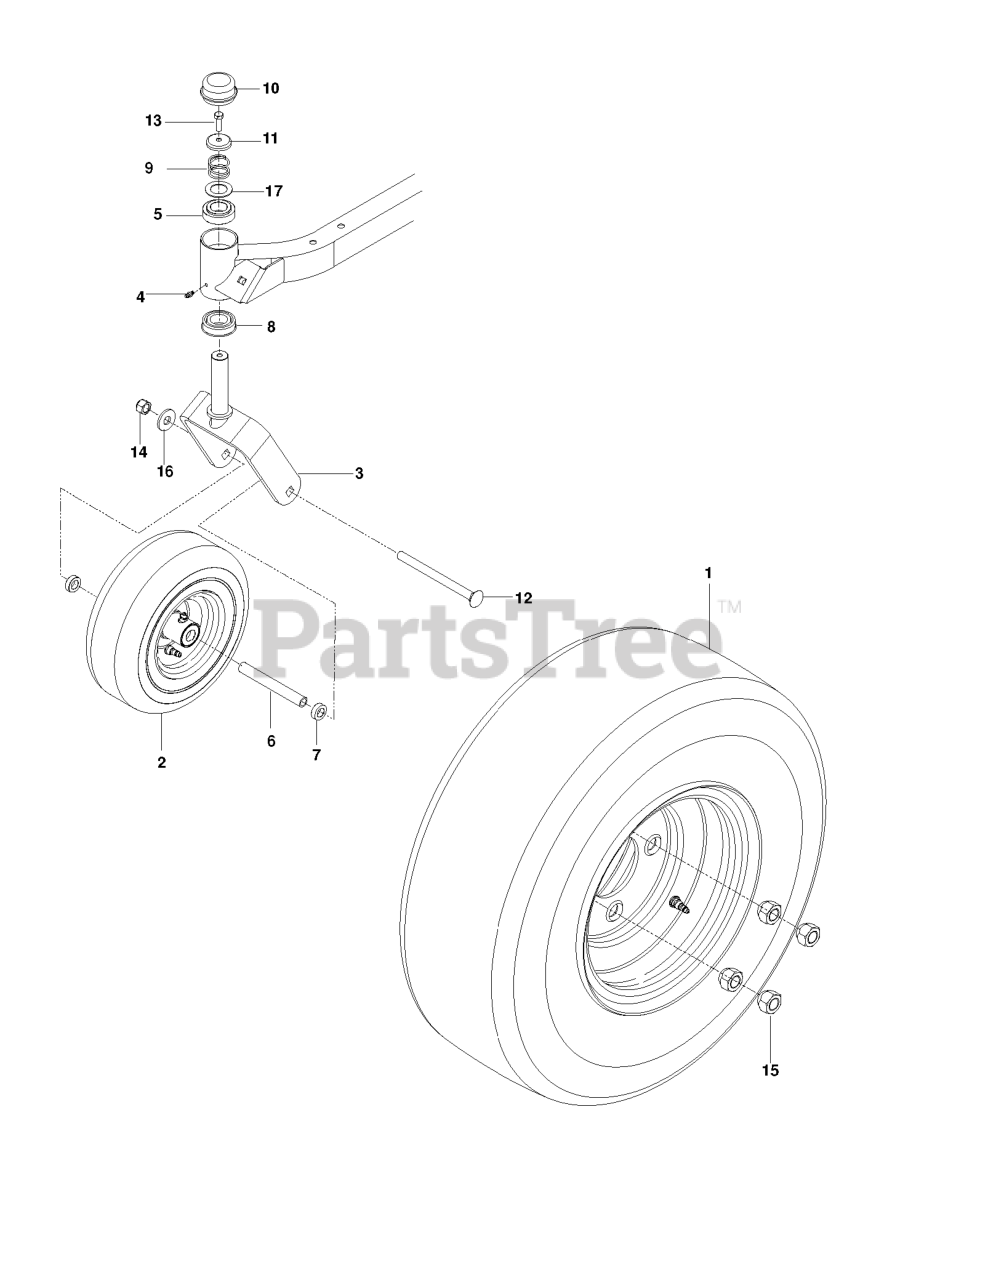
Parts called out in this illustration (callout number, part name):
1	WHEEL.18X6.50-8.4P.K500.8X3.75
2	WHEEL.CARLSTAR.11X4-5".MS417
3	YOKE.CASTER.ORANGE
4	ZERK, 3/16, DRIVE IN
5	BUSHING, CASTER
7	SPACER, 5/16"
8	BEARING FLANGED
9	SPRING, CASTER
10	GREASE CAP
11	CASTER.PLUG
12	RHSNB 1/2-13 X 6.50 GR2 ZD
13	5/16-18X1 HHB G5W/NY
14	NUT 1/2-13 HEX CNTRLK GR 5 ZD
15	LUG NUT 1/2F
16	WASHER.9/16 X 1 3/8 X 12 GA.
17	WASHER, 1.025 ID X 1.64
